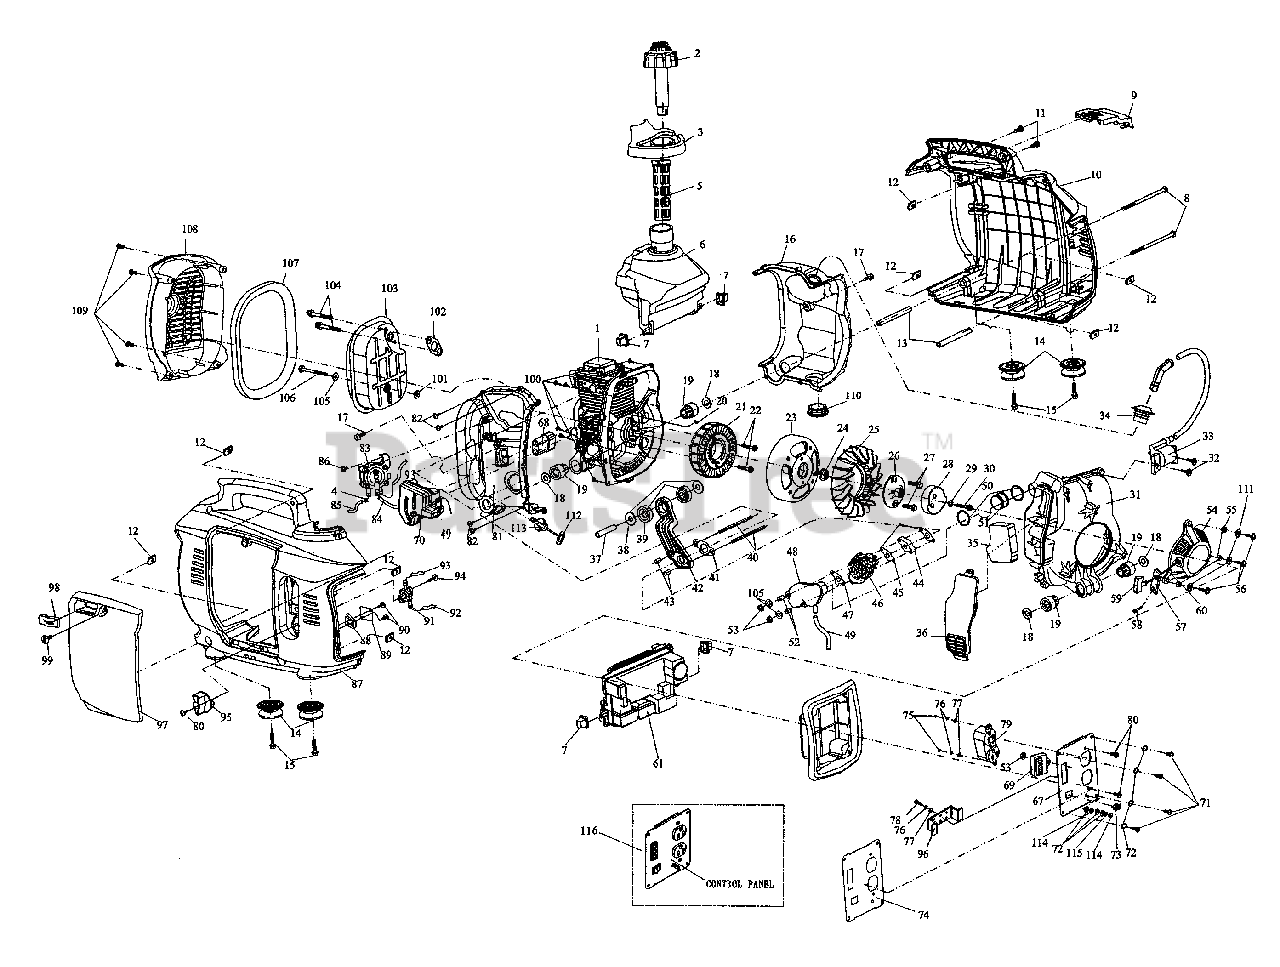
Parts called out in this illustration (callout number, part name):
1	ENGINE ASSY.
2	CAP ASSY, FUEL TANK (RED)
3	FUEL FILLER INLET RUBBER RING
4	CLAMP, FUEL HOSE
5	CUP, FUEL FILTER
6	TANK, FUEL
7	SHOCK ABSORBER BLOCK
8	SCREW, CROSS RECESSED PAN HEAD, M6X120
9	COVER, UPPER SHELL
10	SHELL, UPPER
11	SCREW, CROSS RECESSED PAN HEAD, M6X14
12	LOCK SLICE/SCREW CLIP
13	ALIGNMENT PIN
14	DAMPING FEET
15	BOLT, HEX, FLANGE FACE (M6X12)
16	LOWER CASING, ENGINE
17	BOLT, HEX, FLANGE FACE (M5X16)
19	SLEEVE, DAMPING/VIBRATION MOUNTS
20	KEY, WOODRUFF--3X5X13
21	STATOR ASSY.
22	BOLT, HEX, FLANGE FACE (M5X25)
23	FLYWHEEL ROTOR ASSY.
24	NUT, HEX FLANGE FACE(M10x1.25-8)
26	SEAT, STARTING JAW
27	BOLT, HEX , FLANGE FACE(M6X14)
28	JAW, STARTING
29	WASHER (6)
30	BOLT, HEX, FLANGE FACE(M6X18)
31	COWLING & INLET COVER ASSY.
32	SCREW, CROSS RECESSED PAN HEAD TAPPING
33	COIL, INGITION
34	SLEEVE, RUBBER (HIGH VOLTAGE)
35	SPONGE, AIR FILTER
36	COVER, AIR FILTER
37	ALIGNMENT PIN
39	DAMPING RING, POTHOOK
40	STUD BOLT
41	GASKET, POTHOOK
43	PIN, HOLLOW FIXED POSITION
44	BLOCK, CARBURETOR CUSHION
45	SEAL GASKET, CARBURETOR(OUT)
46	CARBURETOR REGULATING ASSY.
46A	STEPPER MOTOR
47	SEAL GASKET, CARBURETOR(IN)
48	FILTER ADAPTER BOX(BREATHER)
49	TUBE, BREATHER
50	CIRCLIP, ADAPTER
51	SLEEVE, FILTER ADAPTER
52	ALIGNMENT PIN, ADAPTER BOX
53	NUT, HEX FLANGE FACE
54	STARTER ASSY.
55	SAFEGUARD TUBE
56	REC.PAN HEAD SCREW/WASHER ASSY.(M5X12)
57	HANDLE PANEL
58	RECESSED HEAD BOLT & WASHER ASSY.
59	STARTER HANDLE
60	STARTER ROPE
61	INVERTER
